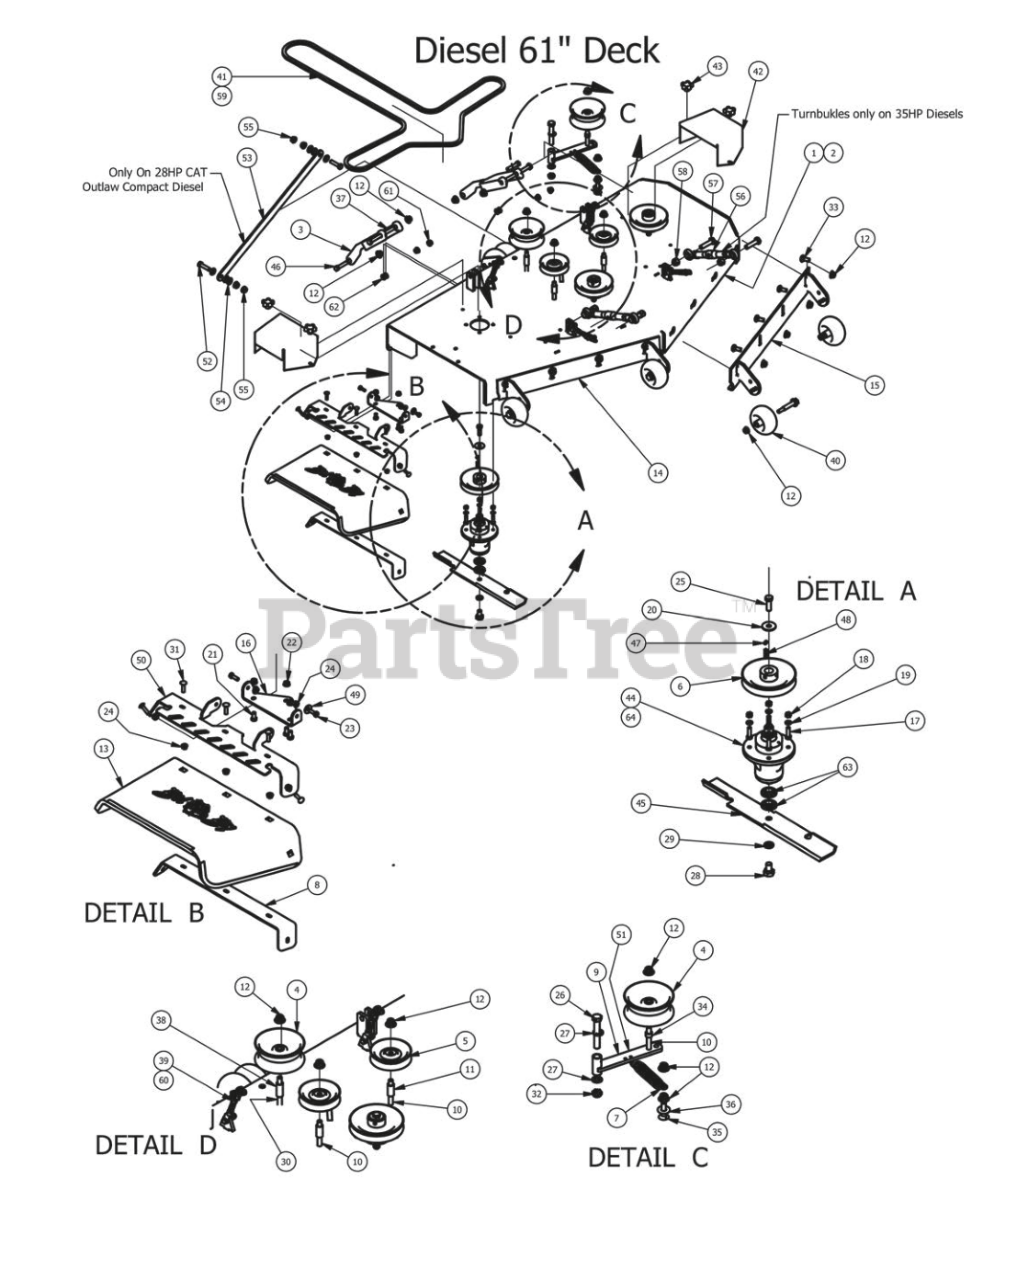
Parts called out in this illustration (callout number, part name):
1	61" Outlaw Deck Only 28HP Diesel
2	61" AOS Deck Only 2012 35Hp Diesel
3	Deck Arm Assembly
4	5 3/4 Flat Idler-32FI-92-008 Pulley
5	4 3/4" Idler Pulley
6	6 1/4" Drive Pulley
7	2009 Deck/Pump Idler Spring
8	60" Lower Hanger
9	Deck Idler
10	1/2 x 3 1/2 Flange Bolt Grade 8
11	.502 ID X.75 OD X 1.500 Leng
12	1/2-13 Nylon Insert Flange Nut
13	Rubber Discharge Chute
14	61 Outlaw Adjustable Deck Front (Left)
15	61 Outlaw Adjustable Deck Front (Right)
16	Discharge Chute Hanger (deck mounted)
17	3/8" x 1 1/4" Hex Bolt
18	3/8-16 Hex Nuts Zinc
19	3/8 Lockwasher Zinc
20	1/2 Belleville Washer
21	3/8" x 3/4" Hex Bolt
22	3/8" Flange Nut
23	5/16" x 1" Bolt
24	5/16" Flange Nut Zinc W/Serrations
25	1/2"-20 x 1 1/2 - Grade 5 Fine Thread Bolt
26	5/8" x 4" Hex Bolt
27	.635 ID Plastic Washer
28	5/8" x 1 1/2" Grade 8 Bolt
29	5/8" Lock Washer
30	1/2" x 4" Bolt (Grade 8)
31	5/16" x 1 1/4" Carriage Bolt
32	5/8" Nylock (1/2 Jam)
33	1/2" x 1 1/4 Carriage Bolt
34	Spacer 3/4 OD X 1/2 ID X.75
35	1/2 x 2" Carriage Bolt
36	1/2" Flat Washer
37	1/2" x 5 1/2" Bolt
38	1 3/4" Pulley Spacer
39	4-Link Adjustable Deck Hange 35HP Diesel
40	Deck Wheel
41	B226 Belt For 2012 (61" 28HP Compact Diesel Only)
42	Pulley Cover
43	5/16" Knob
44	Double Bearing Spindle Only on 28hp Diesel
45	61 inch Fusion Blade
46	1/2-13X 2-1/4 GR Hex Bolts
47	5/16 Set Screw
48	1/4" x 1" Key
49	.360 ID Plastic Washer
50	60" Upper Hanger Plate
51	Deck Idler Assembly-parts of Assembly 12,4,34,10,9
52	1/2-13x2 GR 5 Hex Bolt
53	Panhard Linkage Bar
54	.505 Nylon Spacer
55	1/2" Flange Nut
56	Tumbuckle (Top Link)
57	5/8" x 2 1/2" Hex Bolt
58	5/8 Std NC Nylock Nut
59	B236 Belt - Diesel EZ Ride 35Hp (61" Diesel only)
60	3 Link Adjustable Deck Hanger only on 28HP Diesel
61	Flange Bushing For Deck Arm upper
62	Flange for Lower Deck Arm
63	Double Bearing For Spindle
64	Double Bearing Spindle Only on 35hp Diesel
